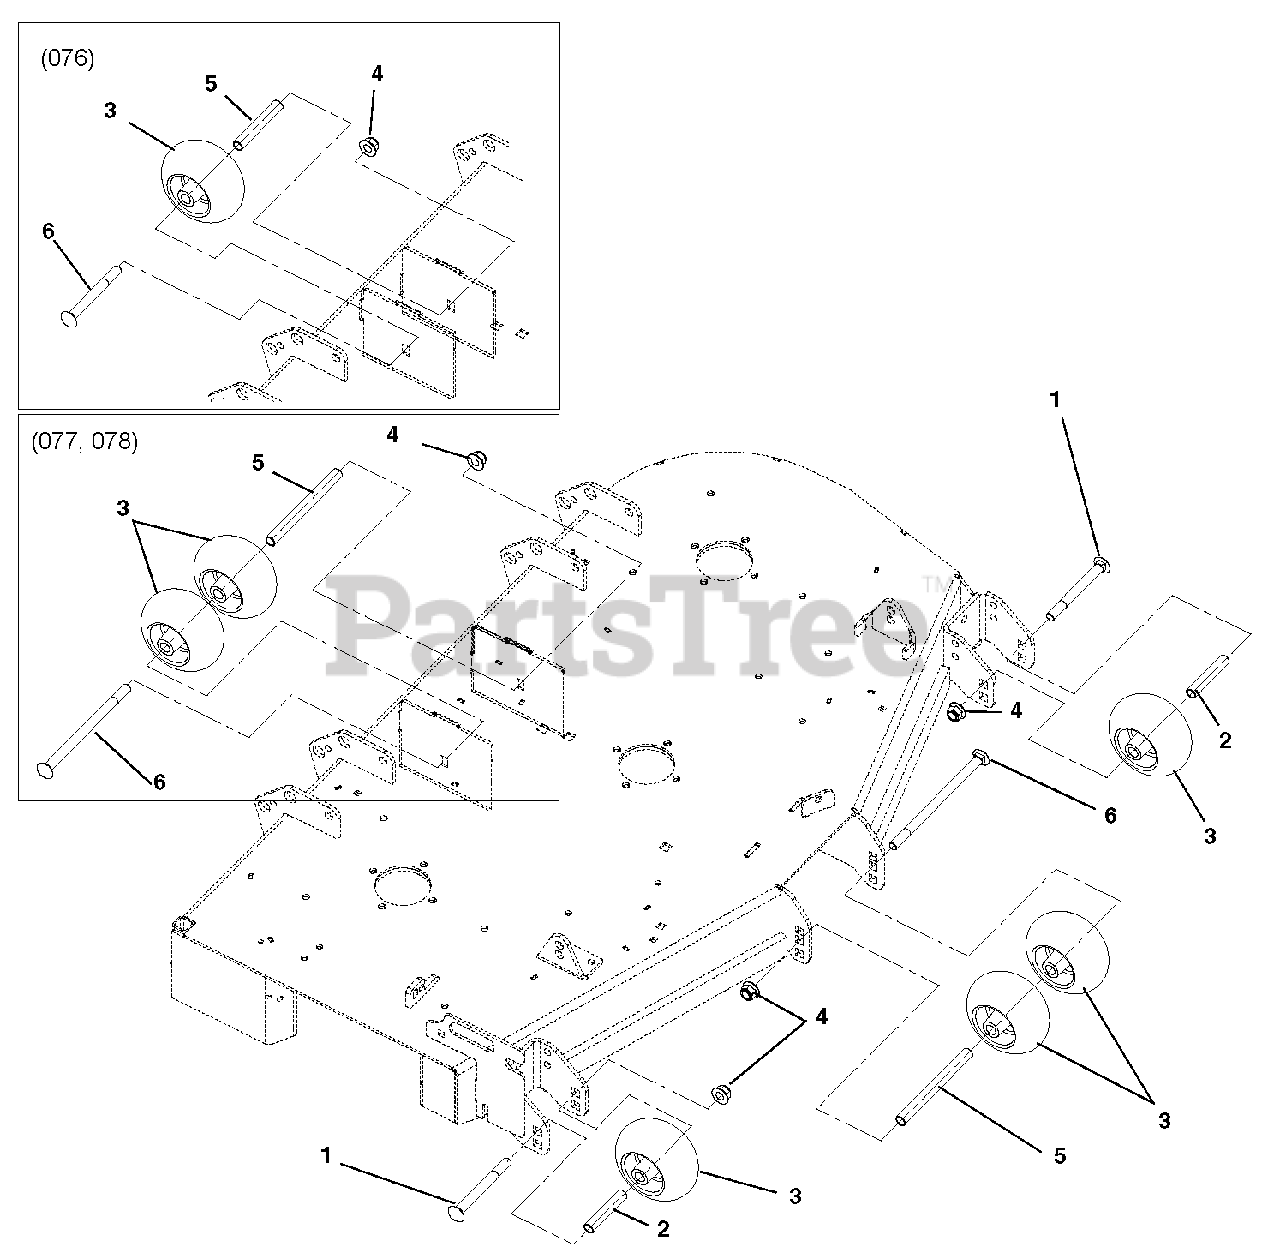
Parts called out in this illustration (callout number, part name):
1	Bolt, Round Head Square Neck .50-13 x 5.00 (076)
2	Spacer, .510 x .625 x 3.35 (076)
3	Anti-Scalp Wheel (076)
4	Nut .50-13 Nyloc Flange
5	Spacer (076)
6	Bolt, Round Head Square Neck .50-13 x 8.50 (076)
